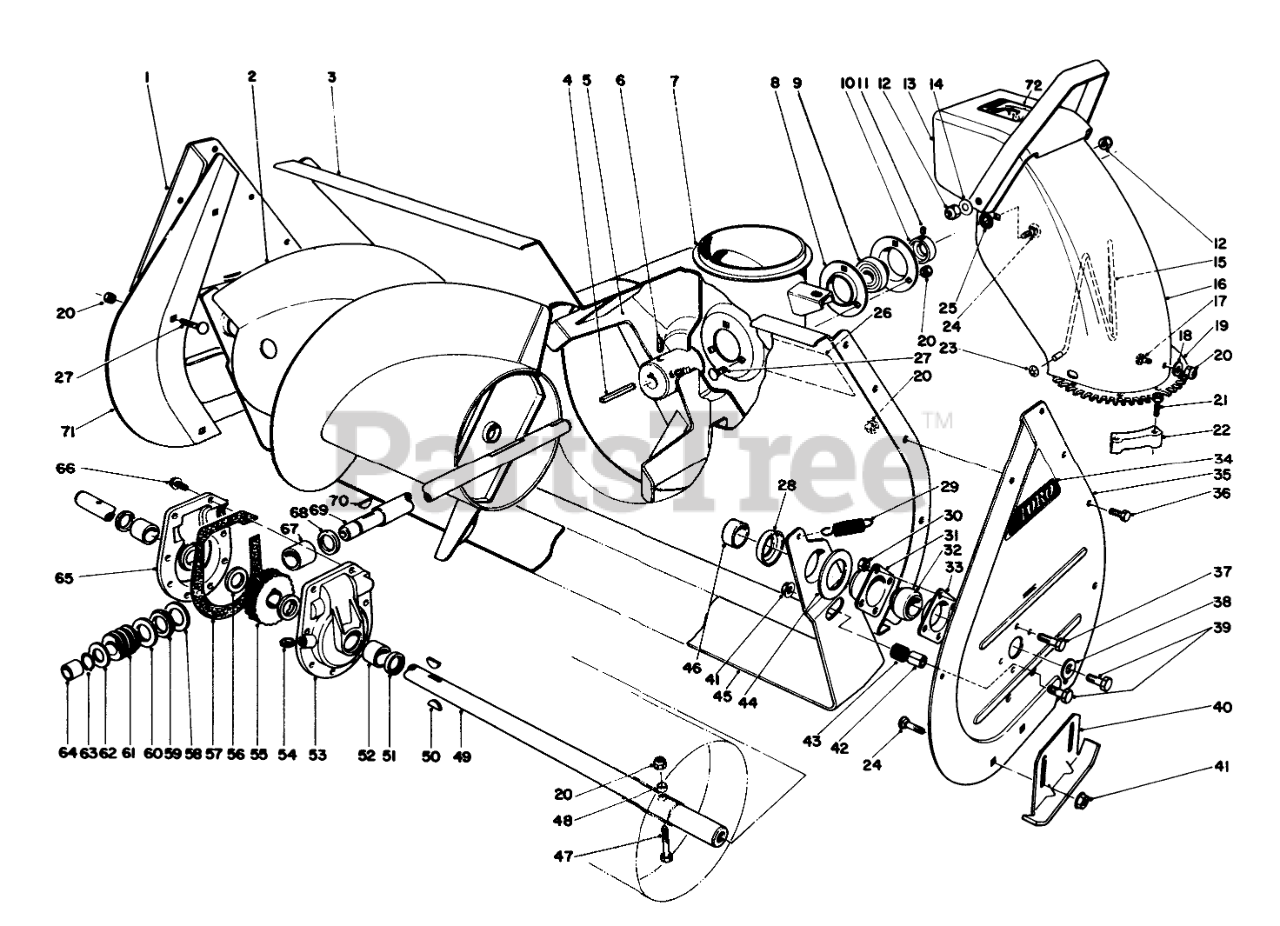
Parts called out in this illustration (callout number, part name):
1	RH AUGER SIDE PLT R
2	RH AUGER ASM - 32"
3	Auger Housing
5	IMPELLER ASM
6	SCREW-SET, SQH
7	CHUTE RING
8	BRG FLANGE
9	Bearing-Impeller (Incl. Ref.10 & 11)
10	EXT LOCKING COLLAR
11	SCREW-HSH
12	NUT-LOCK, CONE
13	Deflector
14	WASHER-BELLEVILLE
15	WIRE-CHUTE
16	Upper Chute
17	SCREW-CARR
18	WASHER-PLAIN
19	Screw
20	NUT-LOCK, NI
21	SCREW-SPECIAL
22	RETAINER-CHUTE
23	NUT-PUSH
24	SCREW-CARR
25	WASHER-RUBBER
26	Decal-Warning
27	BOLT-CARR
28	Positioner-Scraper
29	SPRING-TENSION
30	NUT-LOCK, CONE
31	BEARING-FLANGE, FRONT
32	BEARING
33	BEARING-FLANGE, REAR
34	AUGER SIDE PLT DECAL
35	LH AUGER SIDE PLT R
36	SCREW-HH
37	SCREW-HH
38	WASHER
39	SCREW-HH
40	AUGER SKID WA R
41	NUT-HF
42	SCRAPER STOP SPACER
43	SCRAPER STOP CUSHION
44	SCRAPER BLADE SPACER
45	SCRAPER BLADE 32" R
46	AUGER SPACER
47	Auger Bolt
48	SPACER-HUB, AUGER
49	32 AUGER SHAFT
50	KEY-WOODRUFF
51	SEAL-OIL
52	BUSHING
53	Gear Case Bushing Assy.-L.H. (Incl. Ref. #51, 52)
54	PLUG-PIPE, SQH
55	GEAR-WORM, 27T
56	WASHER-THRUST
57	GASKET-CASE, GEAR
58	WASHER-THRUST
59	BEARING-THRUST
60	THRUST-WASHER
62	WASHER-THRUST
63	Ring-Snap
64	BUSHING
65	Gear Case Bushing Assy.-R.H. (Incl. Ref. #51, 52)
66	SCREW-TAPTITE
67	BUSHING-SPECIAL
68	RING-QUAD
69	SHAFT-IMPELLER
70	KEY-WOODRUFF
71	Auger Housing Extension R.H.
72	Decal-Danger
